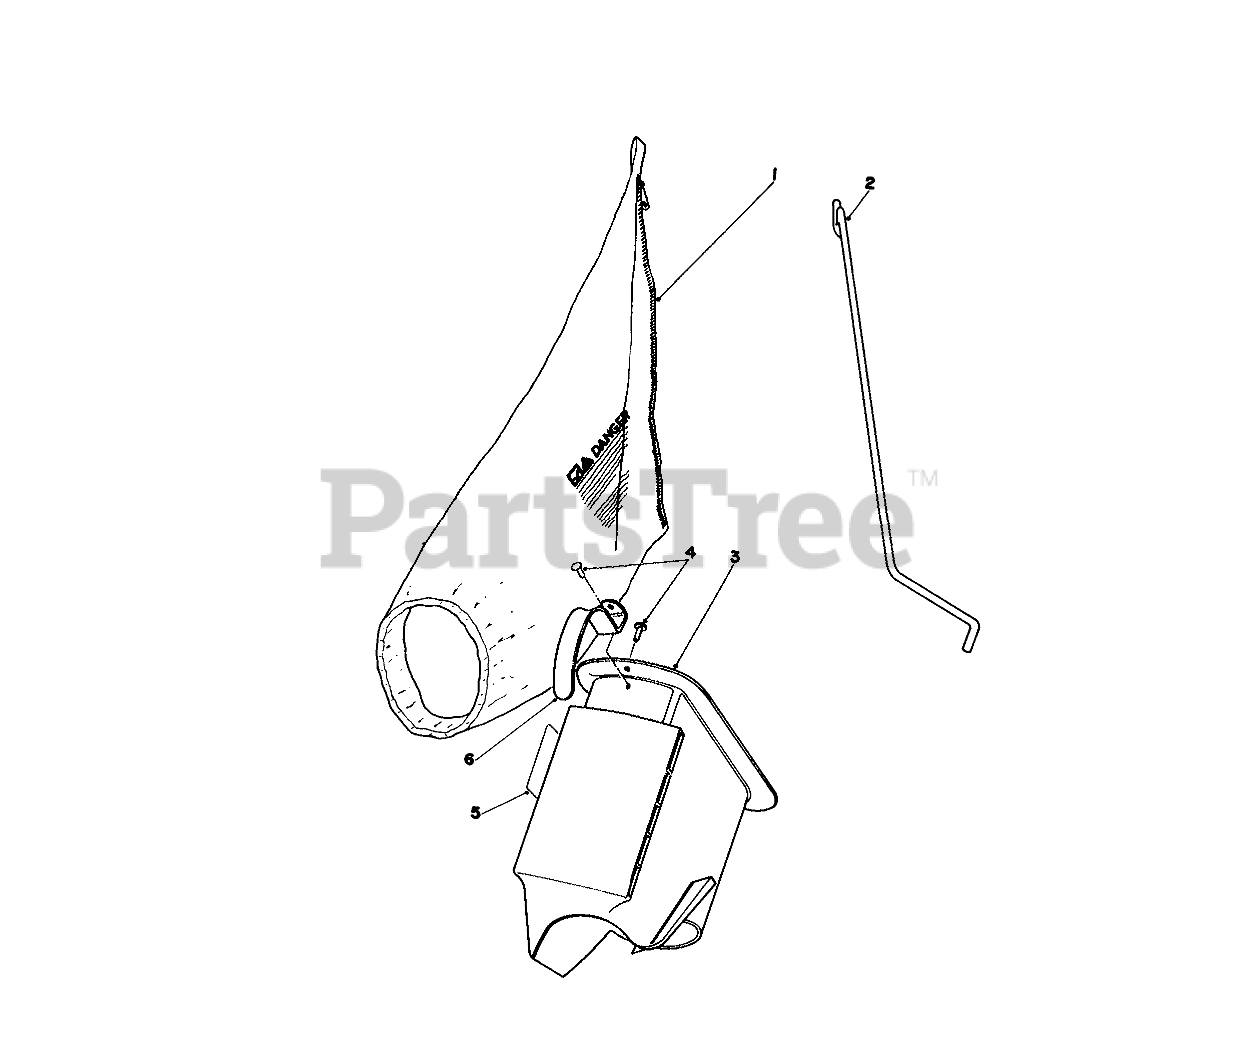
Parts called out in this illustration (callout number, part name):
1	BAG REPLACMNT44-0540
2	Bag Rod
3	Grass Chute (Incl. Ref. #4 & 6)
4	RIVET 3/16 X 7/16
5	Bag Chute Decal
6	HANDLE-GRASS CHUTE
